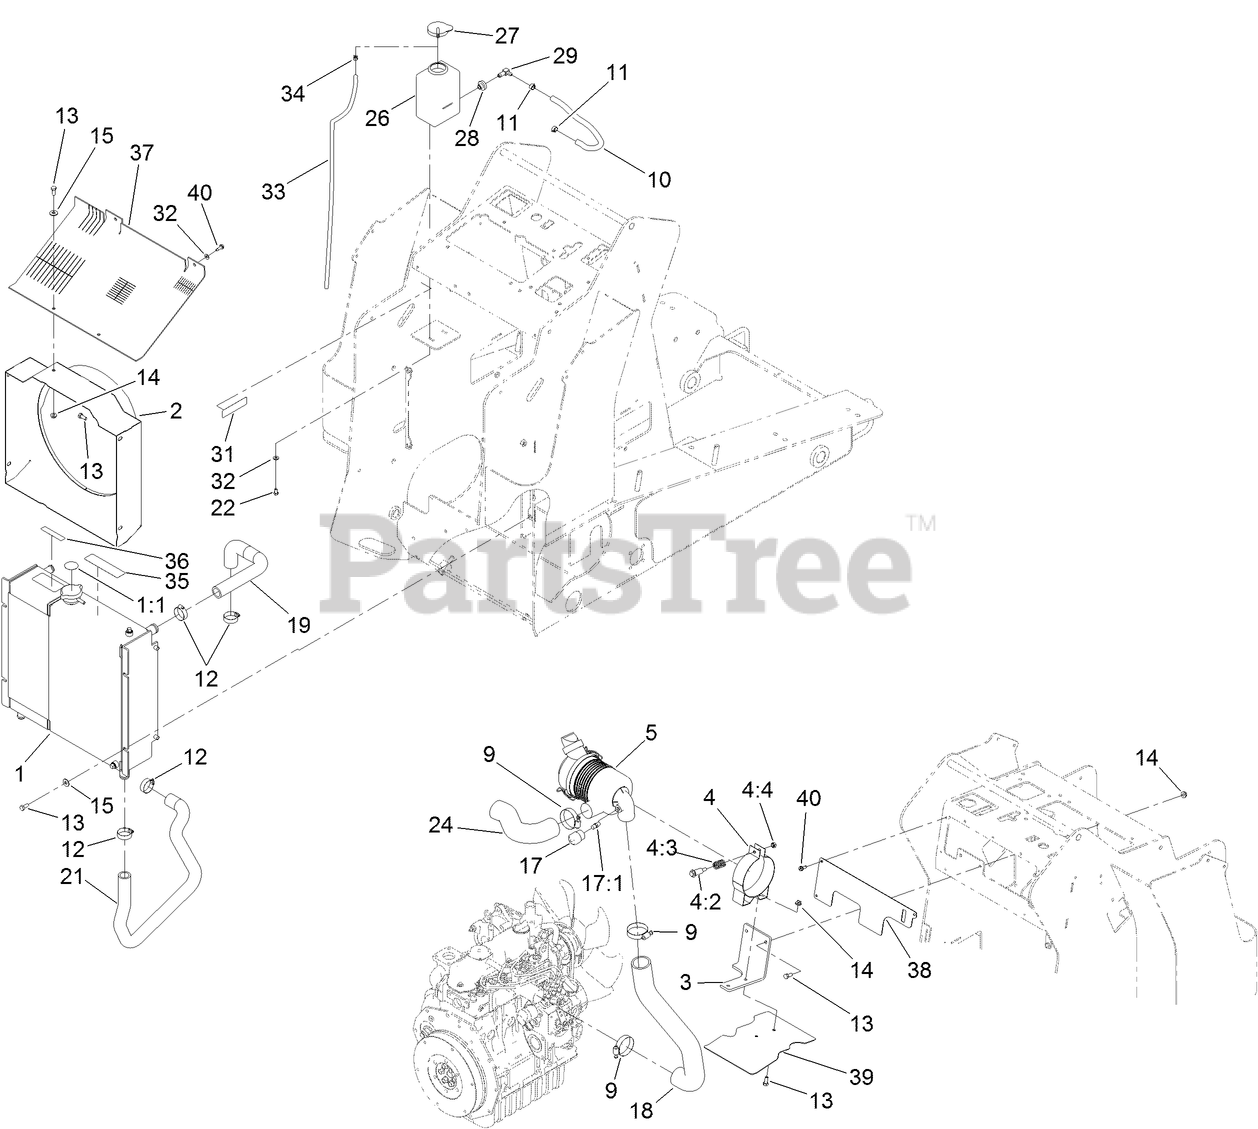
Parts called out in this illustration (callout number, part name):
1	COMBO COOLER ASM
1:1	DECAL-CAP, RADIATOR
4	AIR CLEANER MOUNTING BAND ASM
4:3	SPRING
4:4	NUT
5	AIR CLEANER ASM
9	CLAMP-HOSE
10	HOSE-LP
11	CLAMP-HOSE
12	CLAMP-HOSE
13	SCREW-HH
14	NUT-HF
15	WASHER-FLAT
17	INDICATOR
17:1	ADAPTER-INDICATOR
18	HOSE-INTAKE, ENGINE
19	HOSE-RADIATOR
21	HOSE-RADIATOR, LOWER
22	SCREW-HH
24	HOSE-AIR, INLET
26	TANK-OVERFLOW
27	CAP-TANK, OVERFLOW
28	BUSHING
29	FITTING-ELBOW-90
31	DECAL-RADIATOR FILL
32	WASHER-FLAT
33	HOSE-LP
34	CLAMP-HOSE
35	DECAL-DANGER
36	DECAL-WARNING, FAN
37	GUARD-AIR
38	COVER-AIR
39	BAFFLE-AIR
40	SCREW-HWH
